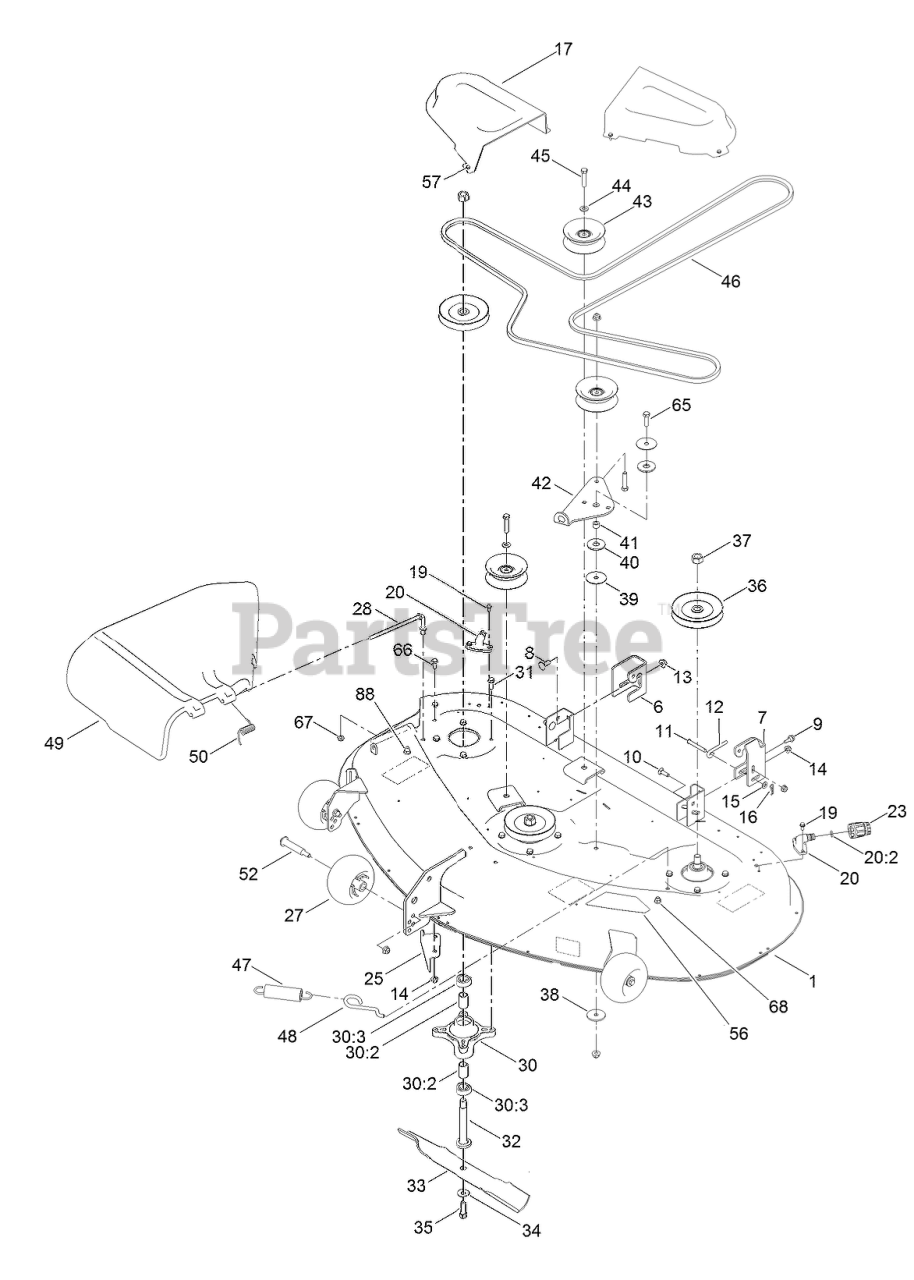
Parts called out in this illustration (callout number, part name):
1	50 INCH DECK AND DECAL ASM
6	BRACKET-HANGER, RH
7	BRACKET-HANGER, LH
8	BOLT-CARR
9	SCREW-SHOULDER,HWH
10	SCREW-CARR
11	PIN-CLEVIS
12	ROD-LEVEL, DECK
13	NUT-HF, NI
14	NUT-HF, NI
15	WASHER-PLAIN
16	PIN-COTTER
17	COVER-BELT
19	SCREW-HWH
20	FITTING-WASHOUT
20:2	O-RING
23	CONNECTOR-HOSE
25	BAFFLE-CUTOFF
27	ROLLER-SCALP, ANTI
28	ROD-PIVOT
30	SPINDLE ASM
30:2	SPACER
30:3	BEARING-BALL
31	SCREW-TAPTITE
32	SHAFT-SPINDLE
33	BLADE-HI LIFT
34	WASHER-BELLEVILLE
35	SCREW-HH
36	PULLEY
37	NUT-HEX
38	WASHER-REBOUND
39	WASHER
40	WASHER-FRICTION, COMPOSITE
41	SPACER
42	ARM-IDLER
43	PULLEY-IDLER, FLAT
44	WASHER-FLAT
45	SCREW-HH
46	V-BELT
47	SPRING-EXTENSION
48	HOOK-RETURN, SPRING
49	DEFLECTOR
50	SPRING-TORSION
52	BOLT-SHOULDER
57	SCREW-TAPTITE
65	SCREW-HH
66	SCREW-HH
68	SCREW-HH
88	SCREW-CARR
